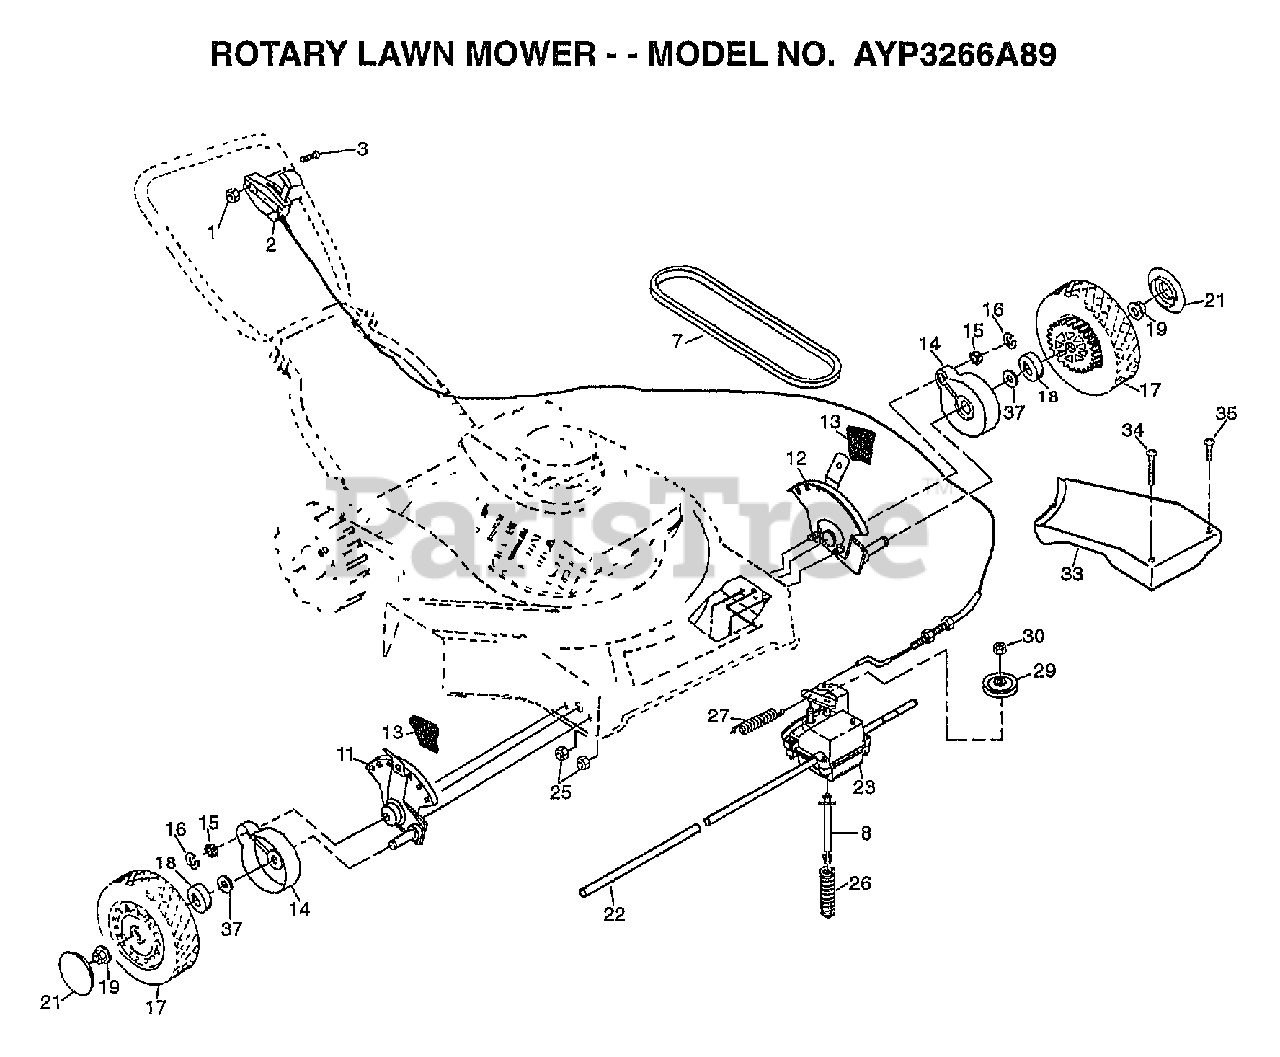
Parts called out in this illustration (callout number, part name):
1	LOCKNUT
2	CONTROL.DRV.56.25
3	PAN HEAD SCREW
8	SPRING.RETAINER.
11	WHEEL.ASSY.RH
12	WHEEL ADJ. ASSY
14	DUST SHROUD PM
15	PINION.GEAR
16	E-RING.7/16.RE.
17	WHEEL.8X2.LP.PR
18	BUSHING.HEX
19	NUT.HXFLG.LOCK.
21	HUB CAP
22	DRV SHAFT TUBE PM
26	SPRING.TENSION
27	SPRING
29	PULLEY.DRIVEN
30	LOCKNUT
33	COVER DRIVE BLK
34	SCREWL.SLOT.TORXT
37	WASHER FLUT
